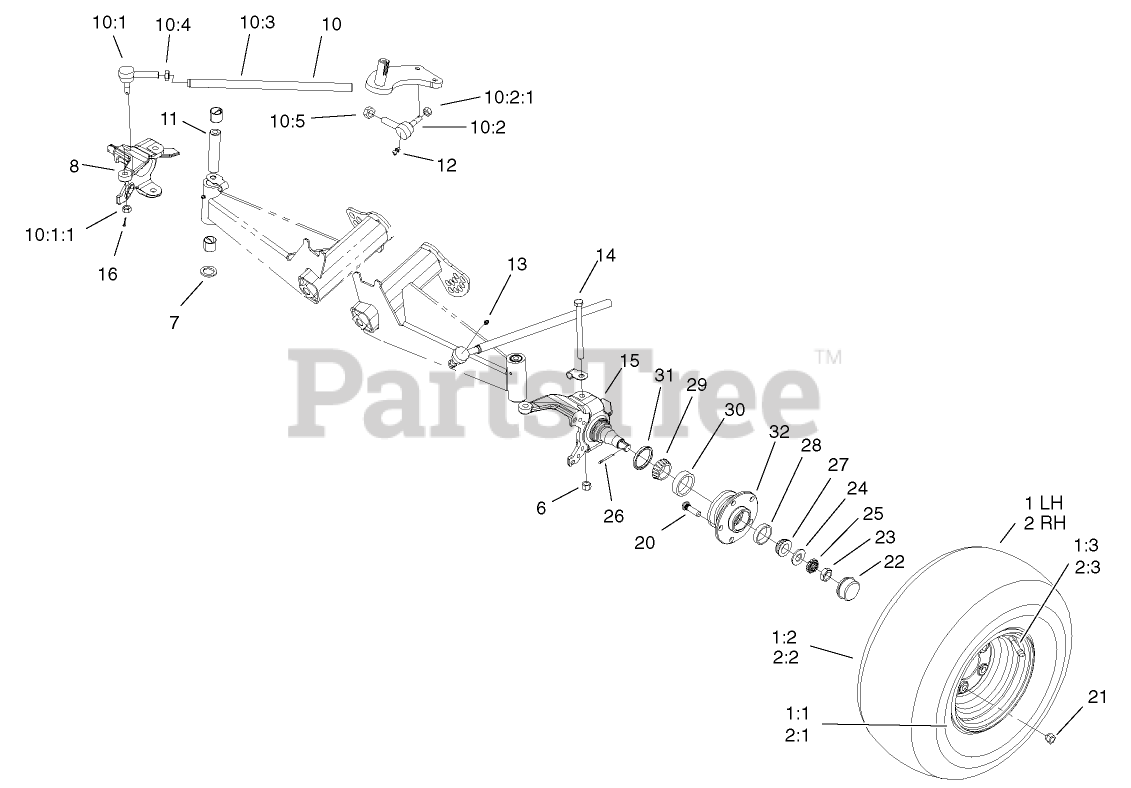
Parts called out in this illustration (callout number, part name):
1:1	WHEEL-5 BOLT
2	Loose Parts Package
2:1	WHEEL-5 BOLT
6	NUT-LOCK, NI
7	WASHER-THRUST
10	Rod-Tie
10:3	ROD-TIE
10:4	NUT-JAM
10:5	NUT-JAM
11	SLEEVE-KINGPIN
12	FITTING-GREASE
13	FITTING-GREASE
14	SCREW-HH
16	PIN-COTTER
20	STUD-TYPE, DRIVE
21	NUT-LUG
22	CAP-DUST
23	NUT-JAM
24	WASHER-TAB
25	NUT-LOCK, RETAINER
26	PIN-COTTER
27	BEARING-CONE, TAPERED
28	BEARING-CUP, TAPERED
29	CONE-BEARING, TAPERED
30	CUP-BEARING, TAPERED
31	SEAL-BEARING
